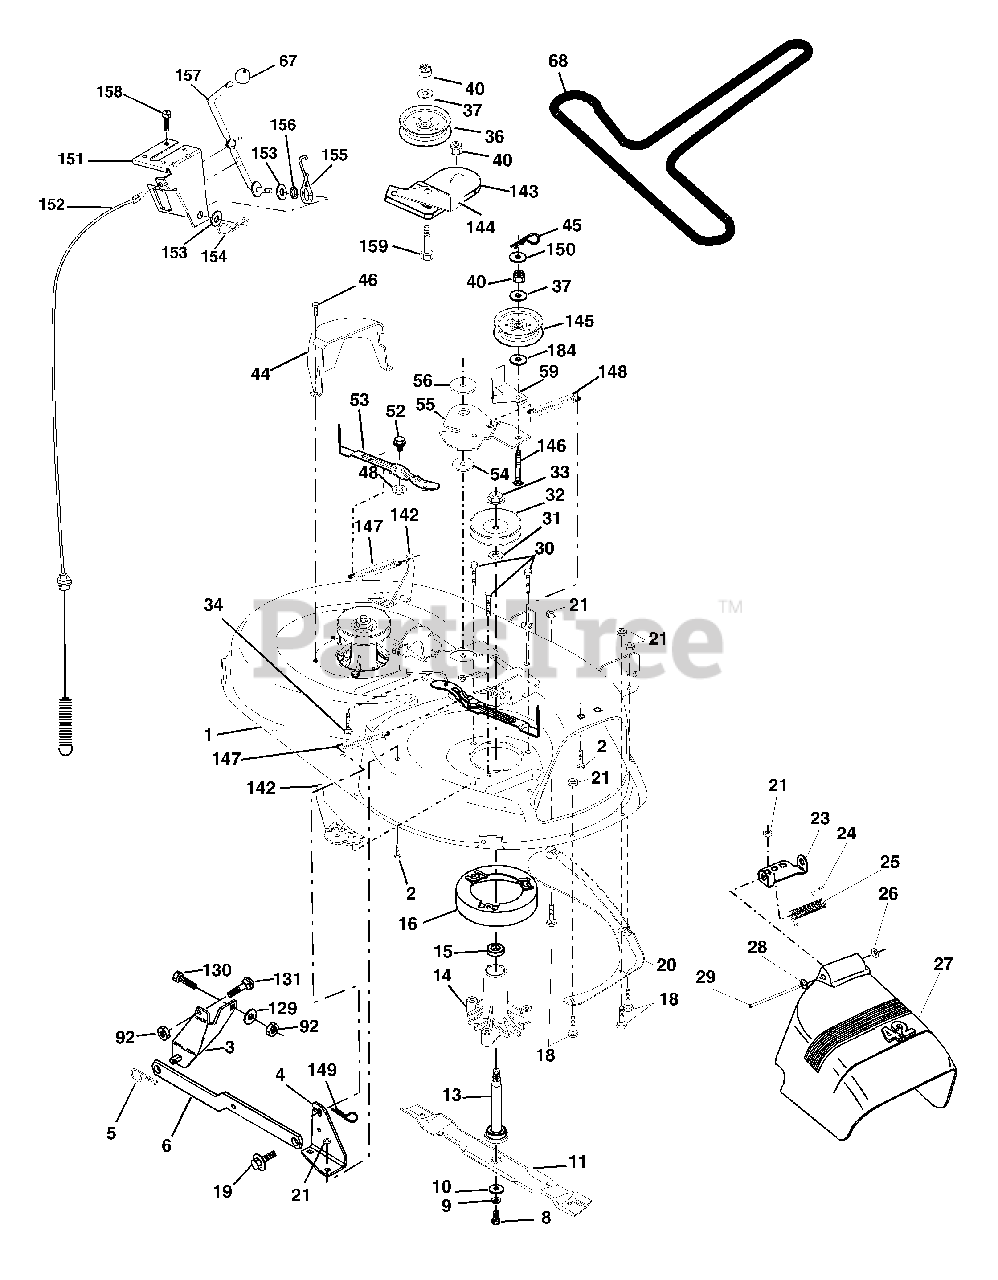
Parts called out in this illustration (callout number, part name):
1	Deck Asm MWR 42" weldment
2	Bolt Rdhd Sqnk 5/16-18 Unc x 3/4
3	Bracket Asm Fr Sway Bar 38/42
4	Bracket Asm Deck 42" sway Bar
5	Retainer Spring
6	Deck Sway Bar
8	Bolt 3/8 - 24 x 1.25 Gr 8
9	Washer Lock Hvy 3/8
10	Washer Hard Blade Mower Vented
11	Blade Mower 42"
11	Blade, 42" Mulching Premium
11	Blade, 42" Hi-Lift
13	Shaft Asm W/lower Bearing
14	Housing Mandrel Vented
15	Bearing Ball Mandrel
16	Stripper Mower
18	Bolt Rdhd Sqnk 5/16-18 x 5/8
19	Bolt Shoulder
20	Baffle Vortex 42
21	Nut Crownlock 5/16-18 Unc
23	Bracket Deflector Mower 42"
24	Cap Sleeve 80 x 112 Blk Mower
25	Spring Torsion Deflector 2 52
26	Nut Push Phos & Oil
27	Shield Deflector Mower 42" Blk
28	Washer 11/32 x 5/8 x 16 Ga
29	Rod Hinge 42" 6 75 Wlg
30	Screw Thd Rolling
31	Washer Spacer Mower Vented
32	Pulley Mandrel 42"
33	Nut Toplock Flng
34	Bolt Rdhd 3/8-16 Unc x 1-3/4 Gr.5
36	Pulley Idler Flat
37	Washer 13/32 x 13/16 x 16
40	Nut Crownlock 3/8-16 Unc
44	Guard Mandrel LH Black
45	Spring Retainer 1" Zinc/cad
46	Screw Hex Thd Cut 1/4-20 x 5/8 T
48	Washer Hardened Smaller
52	Bolt Shoulder 5/16-18 Unc Blkz
53	Arm Asm Pad Brake
54	Washer Hardened
55	Arm Idler 42" mower LT/YT
56	Spacer Retainer Mower
59	Guard TUV Idler
67	Knob Rd 3/8-16 Plstc Thds Blk
68	V-Belt Mower 42"
92	Nut 3/8-16 Unc
129	Washer 13/32 x 13/16 x 12 Ga.
130	Bolt 3/8-16 x 1 Gr.5
131	Bolt 3/8-16 x 1
142	Arm Spring Brake Mower
143	Bracket Arm Idler 42"
144	Keeper Belt 42" Clutch
145	Pulley Idler Flat
146	Bolt Carriage Idler
147	Spring Extension
148	Spring Return Idler
149	Retainer Spring Yellow
150	Washer 9/32 x 3/4 x 16 Ga.
151	Bracket Clutch Cable
152	Clutch Cable 42"
153	Washer Flat 3/8" Type B
154	Spring Retainer
155	Spring Retention Lvr Cltch Cab
156	Spacer Clutch Cable
157	Rod Clutch Cable 3/8"
158	Screw Hex Thd Cut 1/4-20 x 1/2
159	Bolt Rdhd Sqn 3/8-16 Unc x 1-3/4
184	Washer 13/32 x 7/8 x 10 Ga.
